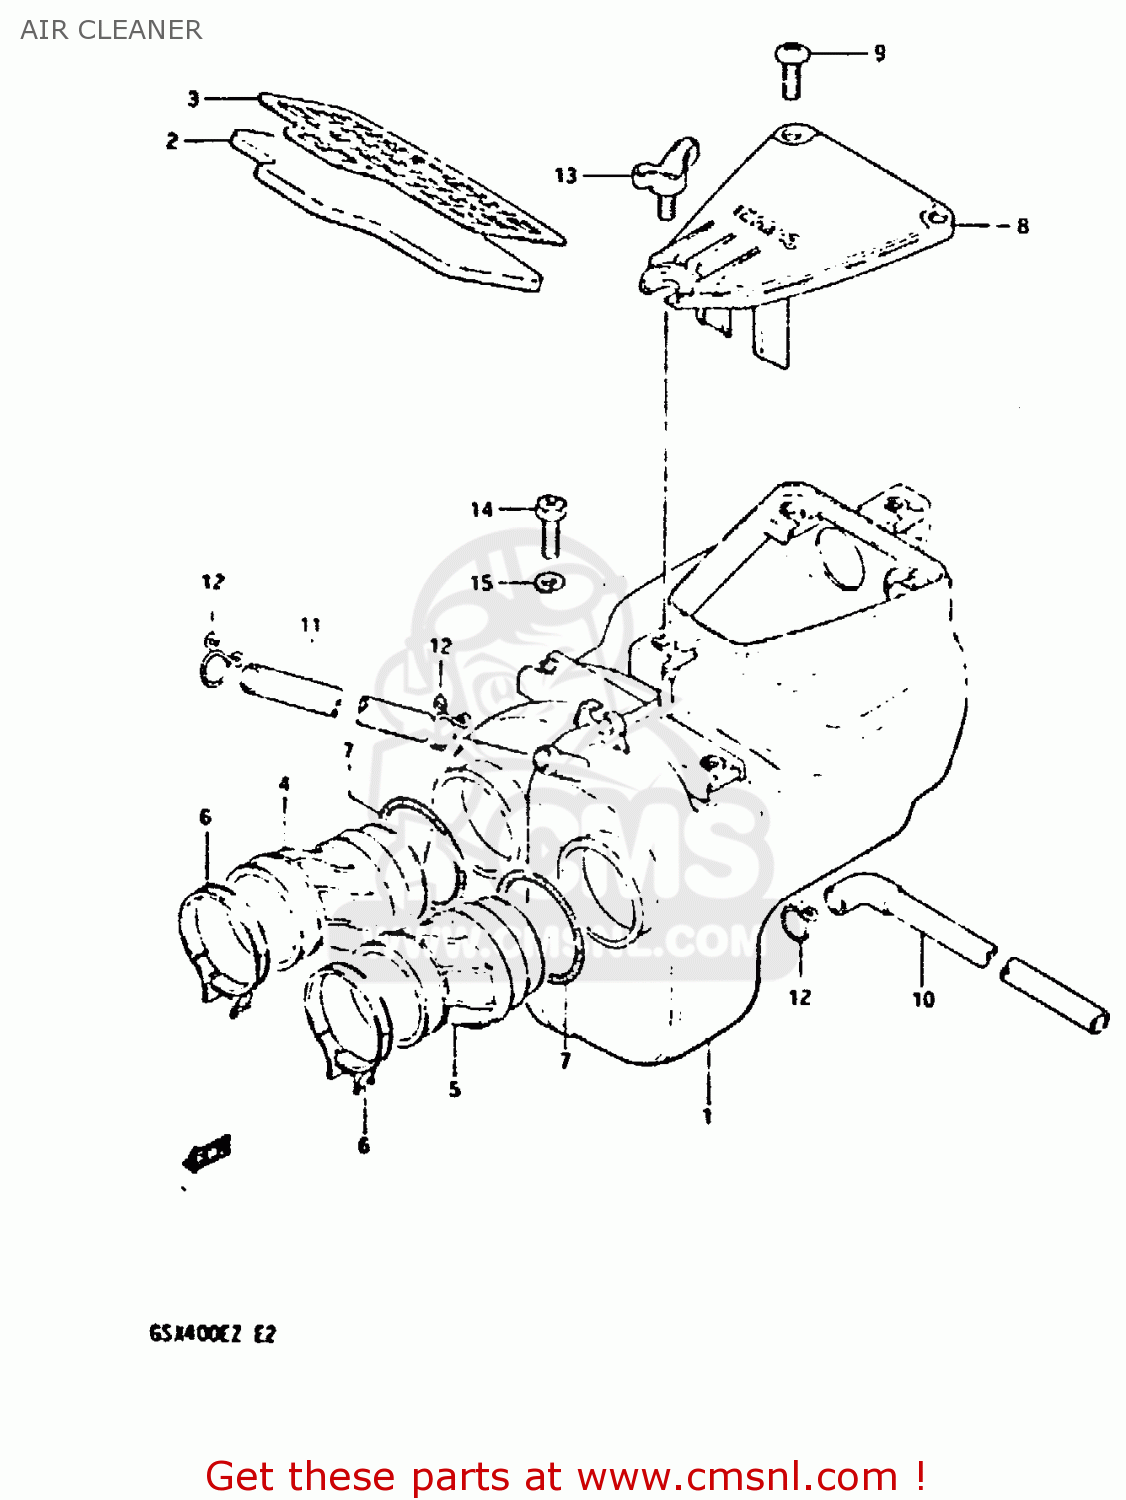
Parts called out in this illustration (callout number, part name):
1	CLEANER ASSEMBLY,AIR
2	FILTER
3	HOLDER,OUTER
4	TUBE,OUTLET,R
5	TUBE,OUTLET,L
6	CLAMP
7	CLAMP,CLEANER SIDE
8	CAP,AIR CLEANER
9	SCREW
10	DRAIN TUBE
11	TUBE,BREATHER
12	CLAMP
13	BOLT, WING
14	BOLT L:16
15	LOCK WASHER
